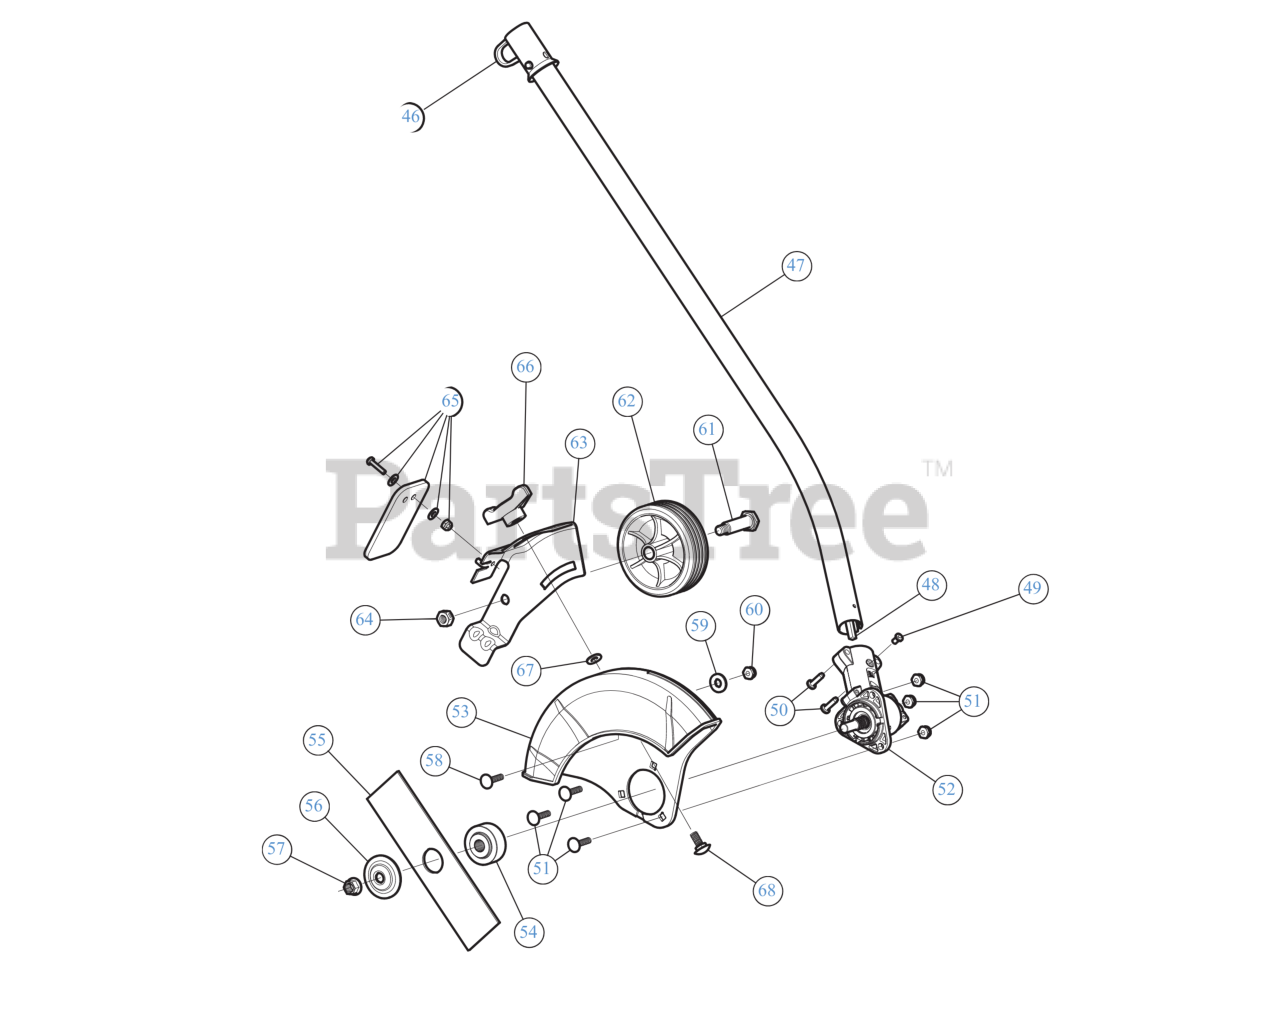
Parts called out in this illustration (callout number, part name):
46	PLUG CAP
47	BOOM ASSEMBLY
48	LOWER DRIVE SHAFT
49	SCREW, 8-32 x .312 P
50	SCREW #
51	HDWR ASM:GUARD MT
52	GRBX ASSEMBLY
54	SPACER
55	EDGER BLADE
56	WASHER-BLADE CLAMP BRUSH CUT
57	BLADE LOCK NUT
58	CARRIAGE BOLT 1/4-20 x 1
59	FLAT WASHER
60	NUT 1/4-20 NYLOC
61	BOLT
62	WHEEL 3.75" (WHITE)
63	BRACKET GUARD
64	LOCK NUT 3/8-16
65	DEFLECTOR W/HDW
66	WING KNOB 5/16-18
67	WASHER .406X1.0X.095
68	CARRIAGE BOLT 5/16-18 x .75
